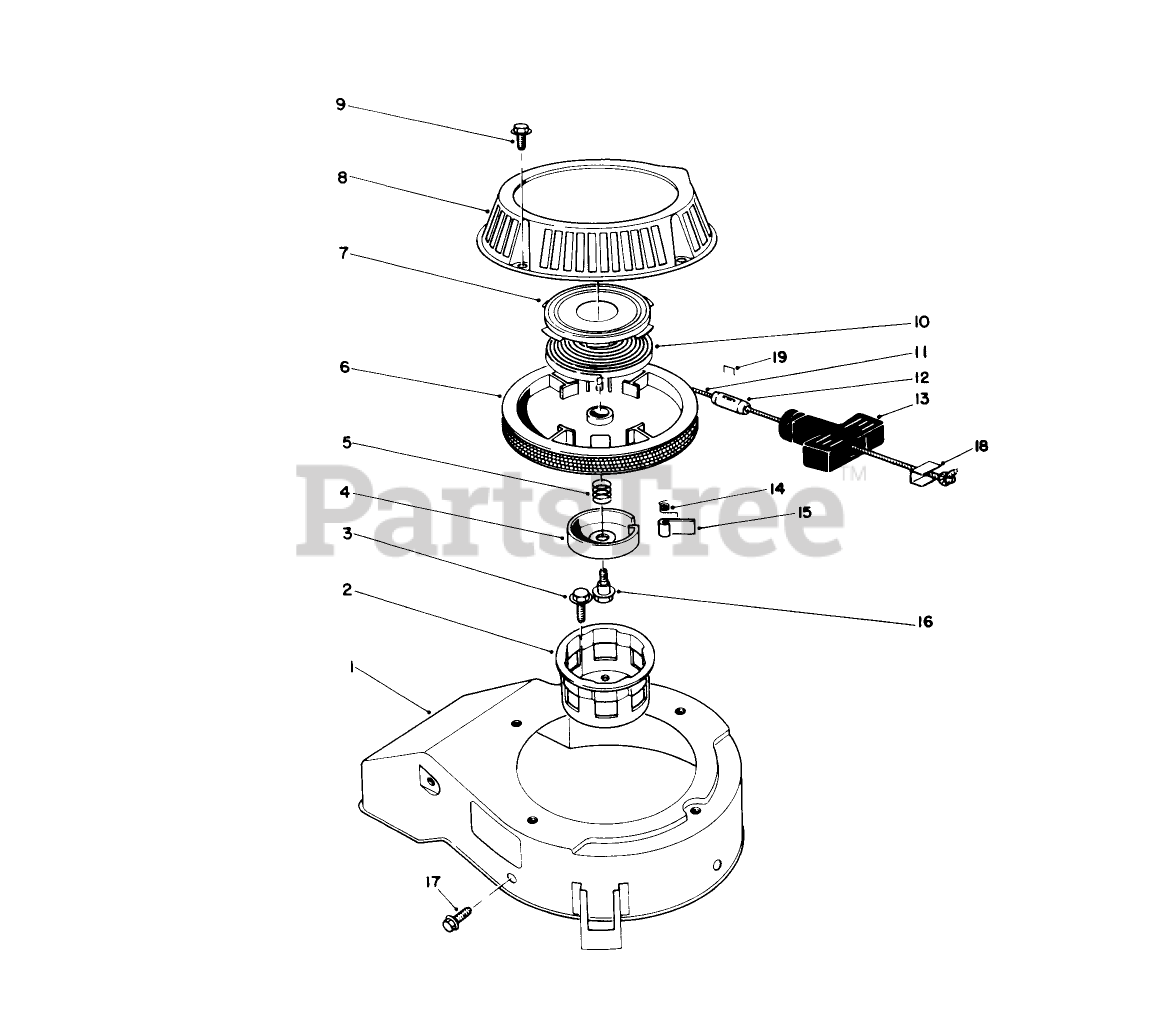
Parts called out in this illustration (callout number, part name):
1	COVER
2	CUP - STARTER
4	RETAINER
5	SPRING
7	Retainer Cup-Recoil Spring
9	SCREW-HHF
10	Spring-Recoil
11	ROPE-STARTER
13	HANDLE-RECOIL
14	SPRING
18	Insert Handle
19	Staple
